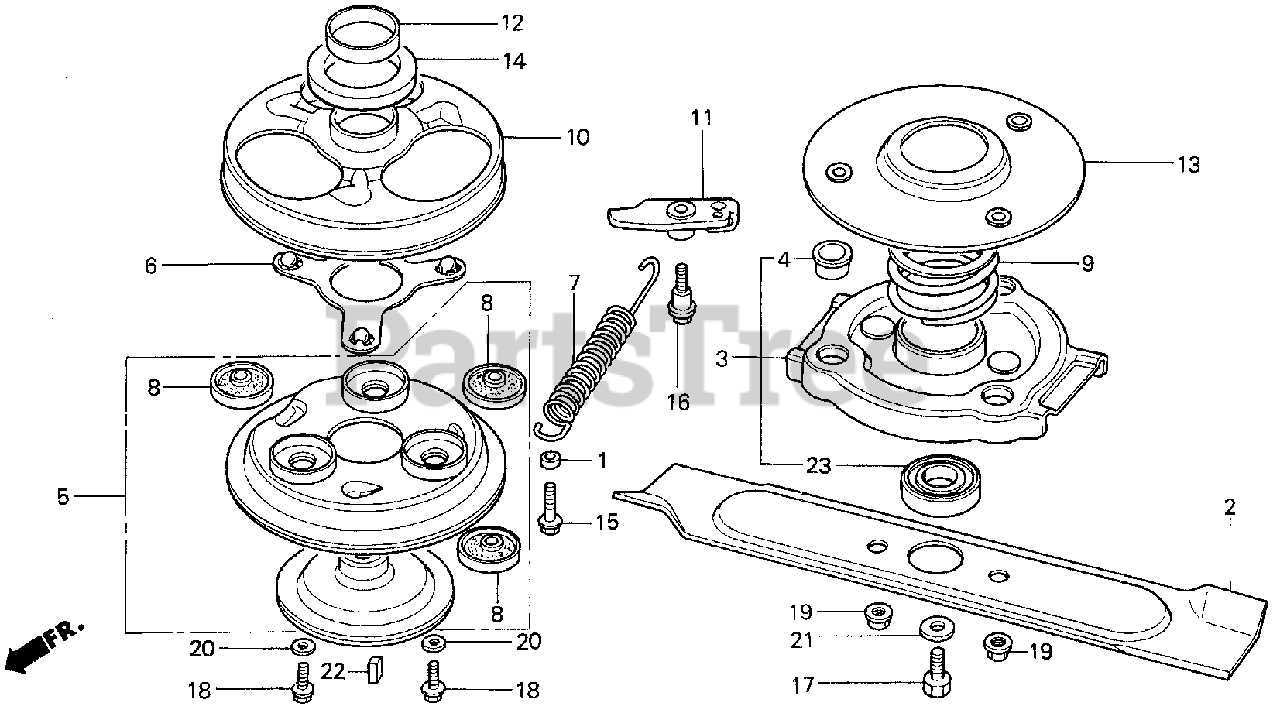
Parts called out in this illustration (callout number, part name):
1	COLLAR, FAN
2	BLADE, ROTARY
3	HOLDER ASSY., BLADE (NOT AVAILABLE)
4	BUSH, BLADE HOLDER (NOT AVAILABLE)
5	DISK SET, BRAKE & DRIVE (NOT AVAILABLE)
6	RETAINER, BALL (NOT AVAILABLE)
7	SPRING, ROTO-STOP RETURN
8	RUBBER, CLUTCH (NOT AVAILABLE)
9	SPRING, CLUTCH
10	PLATE, BALL CONTROL (NOT AVAILABLE)
11	PLATE, LINK (NOT AVAILABLE)
12	BUSH, CENTER
13	DISK, DRIVEN
14	HOLDER, BALL (NOT AVAILABLE)
15	BOLT, FLANGE (6X16) (CT200)
16	BOLT, LINK CENTER (NOT AVAILABLE)
17	BOLT, HEX. (8X25)
18	BOLT, FLANGE (6X25) (CT200)
19	NUT, HEX. (8MM)
20	WASHER (6MM)
21	WASHER, ROTOR SETTING
23	BEARING, RADIAL BALL (6203UU)
